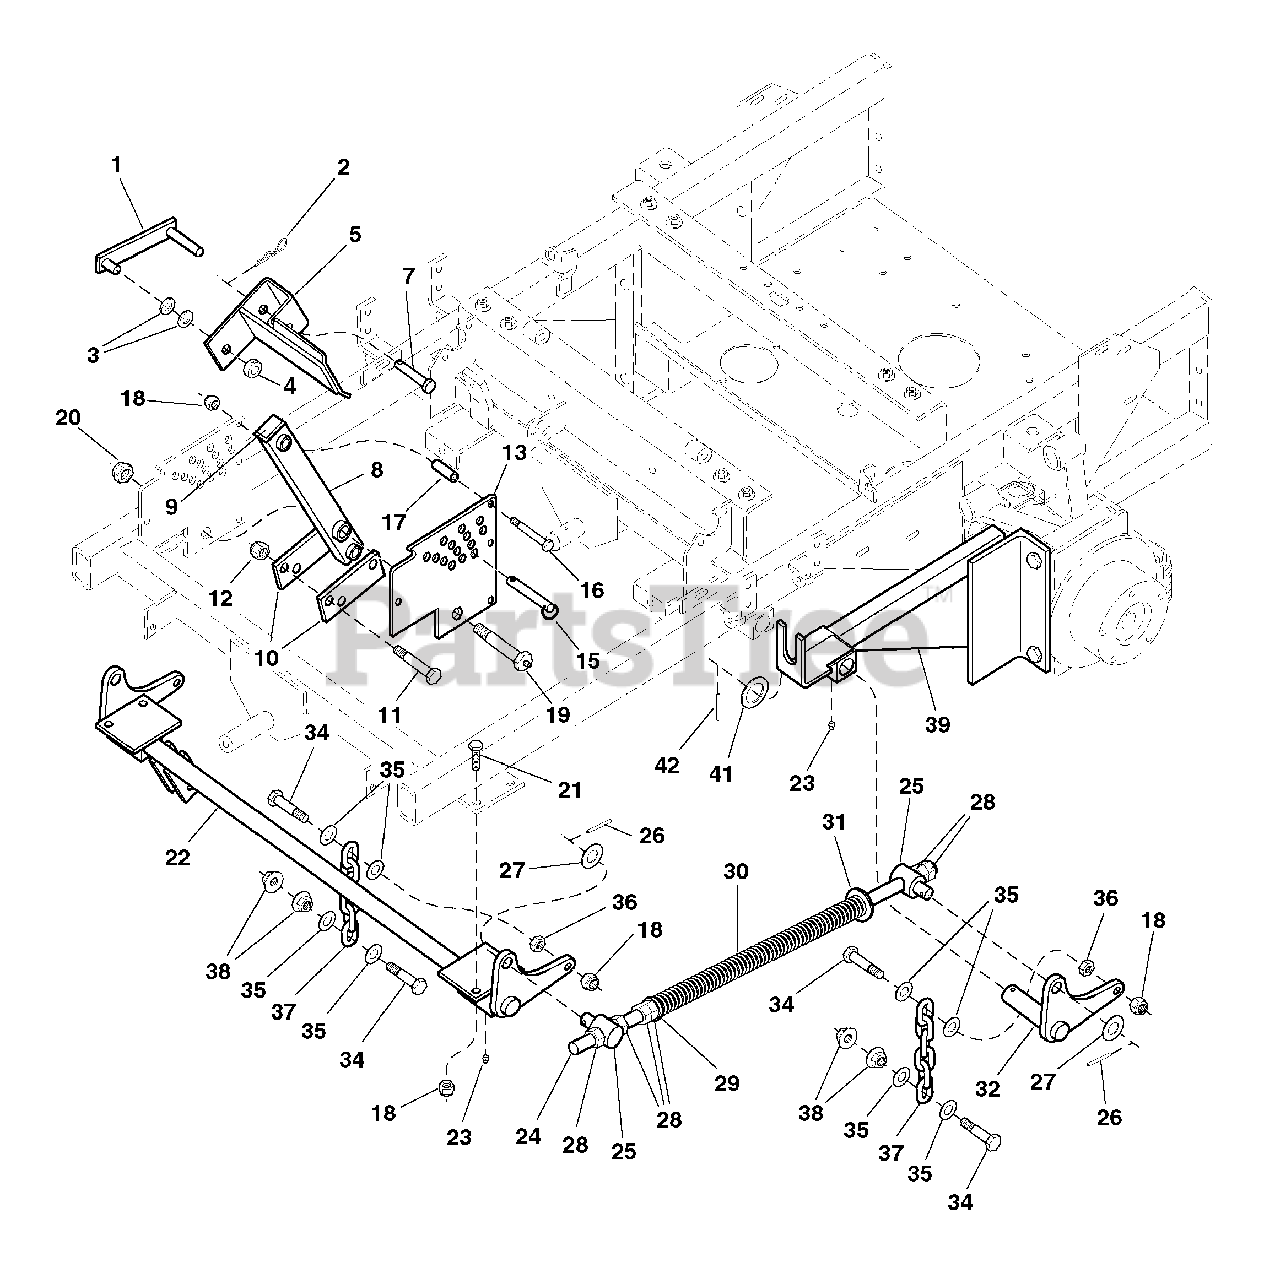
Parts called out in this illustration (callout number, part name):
1	DECK LIFT LOCK
2	HAIRPIN CLIP
3	WASHER, 1/2
4	COLLAR, 1/2 Set
5	DECK LIFT PEDAL
7	PIN, Clevis, 1/2 x 2-1/2
8	ARM, Deck Lift Pivot
10	LINK, Deck Lift
11	CAPSCREW, Hex Hd, 1/2-20 x 3
12	NUT, Hex, Nylon Lock, 1/2-20
13	DECK HEIGHT PLATE
15	PIN, 1/2 x 3
16	CAPSCREW, Hex Hd, 3/8-16 x 2-3/4
17	SPACER, Lift Plate
18	NUT, Hex, Nylon Lock, 3/8-16
19	LIFT PIVOT BOLT
20	NUT, Hex Jam, Nylon Lock, 5/8-11
21	CAPSCREW, Hex Hd, 3/8-16 x 1-1/4
22	DECK LIFT SHAFT & MOUNT ASSEMBLY
23	CREASE FITTING
25	SPRING ROD PIVOT
26	PIN, Spring, 3/16 x 1-1/4
27	WASHER, 5/8
28	NUT, Hex, 5/8-11
30	SPRING, Deck Lift
31	WASHER, USS, 5/8
32	DECK LIFT PIVOT-LH
34	CAPSCREW, Hex Hd, 3/8-16 x 1-3/4
35	WASHER, 3/8
36	NUT, Hex Jam, 3/8-16
37	CHAIN, 6 Links
38	NUT, Hex, Serrated Flange, 3/8-16
39	REAR DECK LIFT FRAME-LH
42	PIN, Roll, 3/16 x 1-1/2
